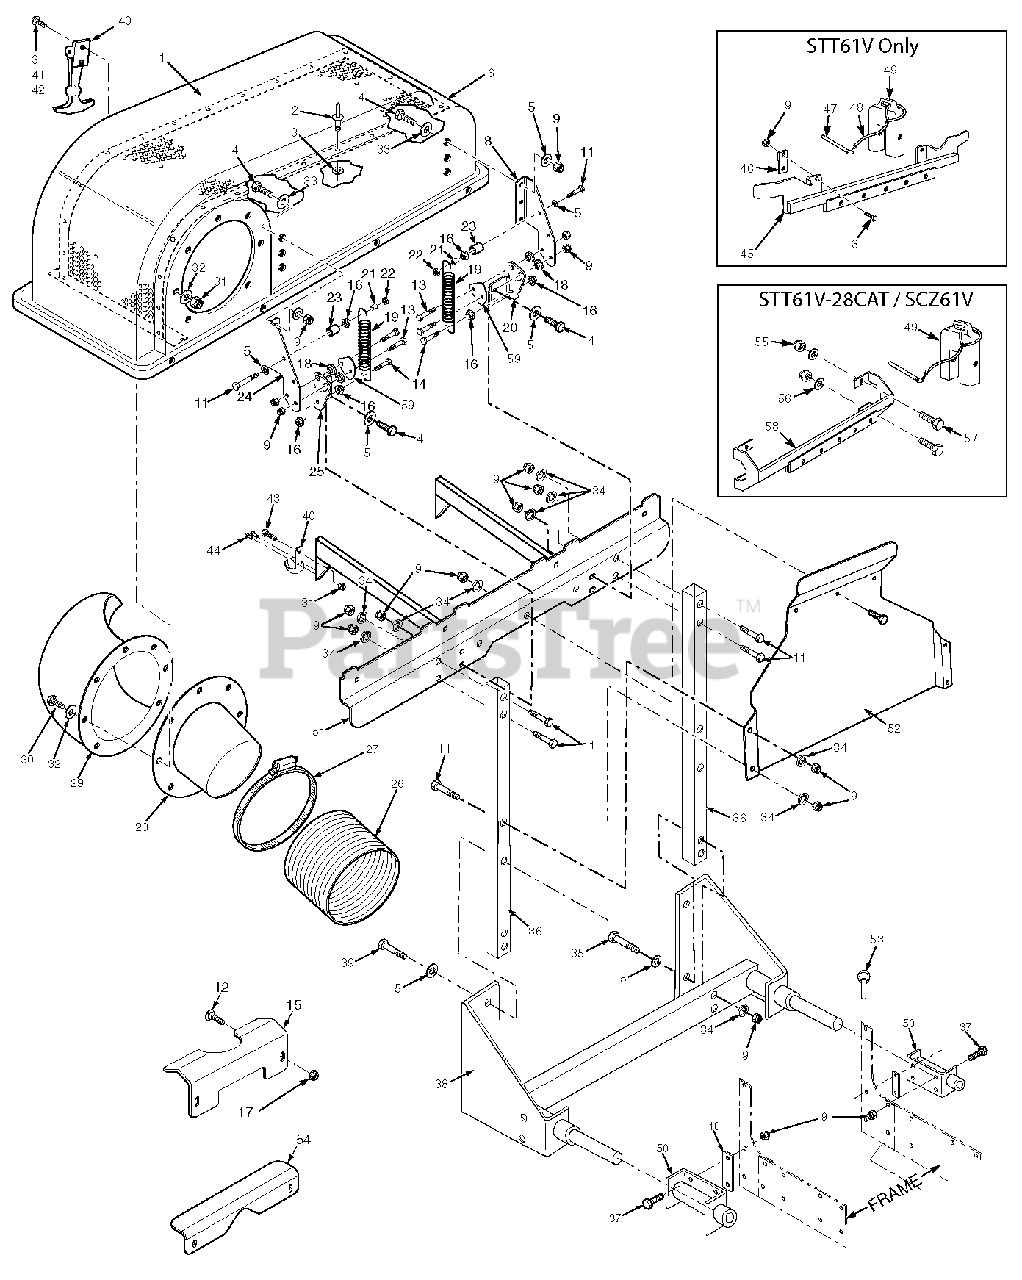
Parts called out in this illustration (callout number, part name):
1	Screen, Catcher Hood
2	Pop Rivet, 3/16 x .652
3	Flatwasher, 3/16-.196 x .469 x .048
4	Bolt, Hex Head 3/8-16 x 1-1/4"
5	Flatwasher, 3/8-.391 x .938 x .105
6	Hood Assembly, GC-STT
7	Bolt, Hex Head 7/16-14 x 1-3/4"
8	Hinge, Upper LH
9	Nut, Elastic Stop 3/8-16
10	Spacer, Hitch
11	Bolt, Hex Head 3/8-16 x 2-1/4"
12	Bolt, Carriage 5/16-18 x 1.00"
13	Bolt, Hex Head 3/8-16 x 1-1/2"
14	Bolt, Hex Head 3/8-16 x 1-3/4" Grade 8
15	Support Bracket, Catcher
16	Nut, Serrated Flange 3/8-16
17	Nut, Hex Serrated Flange 5/16-18
18	Bushing, Hopper Pivot
19	Spring, Hood Hinge
20	Hinge, Lower LH
21	Spacer
22	Locknut, 3/8-16
23	Spacer
24	Hinge, Upper RH
25	Hinge, Lower RH
26	Hose, 8" Dia. x 53"
27	Clamp, 8-5/8" Max Dia.
28	Tube, Filler
29	Elbow
30	Bolt, Hex Head 5/16-18 x 1-1/4"
31	Nut, Elastic Stop 5/16-18
32	Flatwasher, 5/16-.375 x .875 x .083
33	Flatwasher, 3/8- .406 x 1-1/2" x .179
34	Lockwasher, 3/8" Spring
35	Bolt, Hex Head 3/8-16 x 3-3/4"
36	Tube, Upright
37	Bolt, Hex Head 3/8-16 x 1"
38	Bolt, Hex Head 3/8-16 x 2-1/2"
39	Support Weldment, Weights
40	Latch
41	Screw, #10-32 x 3/4"
42	Nut, Elastic Stop #10-32
43	Bolt, Hex Head 5/16-18 x 3/4"
44	Rivet, 3/16 x .402 POP
45	Support Weldment, Front Weights
46	Clamp, Bar
47	Pin, 1/2 x 6-1/4"
48	Lanyard, Weight Pin
49	Weight Assembly
50	Hitch Bracket Weldment
51	Support Weldment, Bag Frame
52	Heat Shield
53	Quick Pin
54	Support Bracket, GC
55	Nut, Elastic Stop 7/16-14
56	Flatwasher, 7/16-.500 x 1.250 x .083
57	Bolt, Hex Head 7/16-14 x 1-3/4"
58	Support Weldment, Front Weights
59	Guard, GC Hinge
